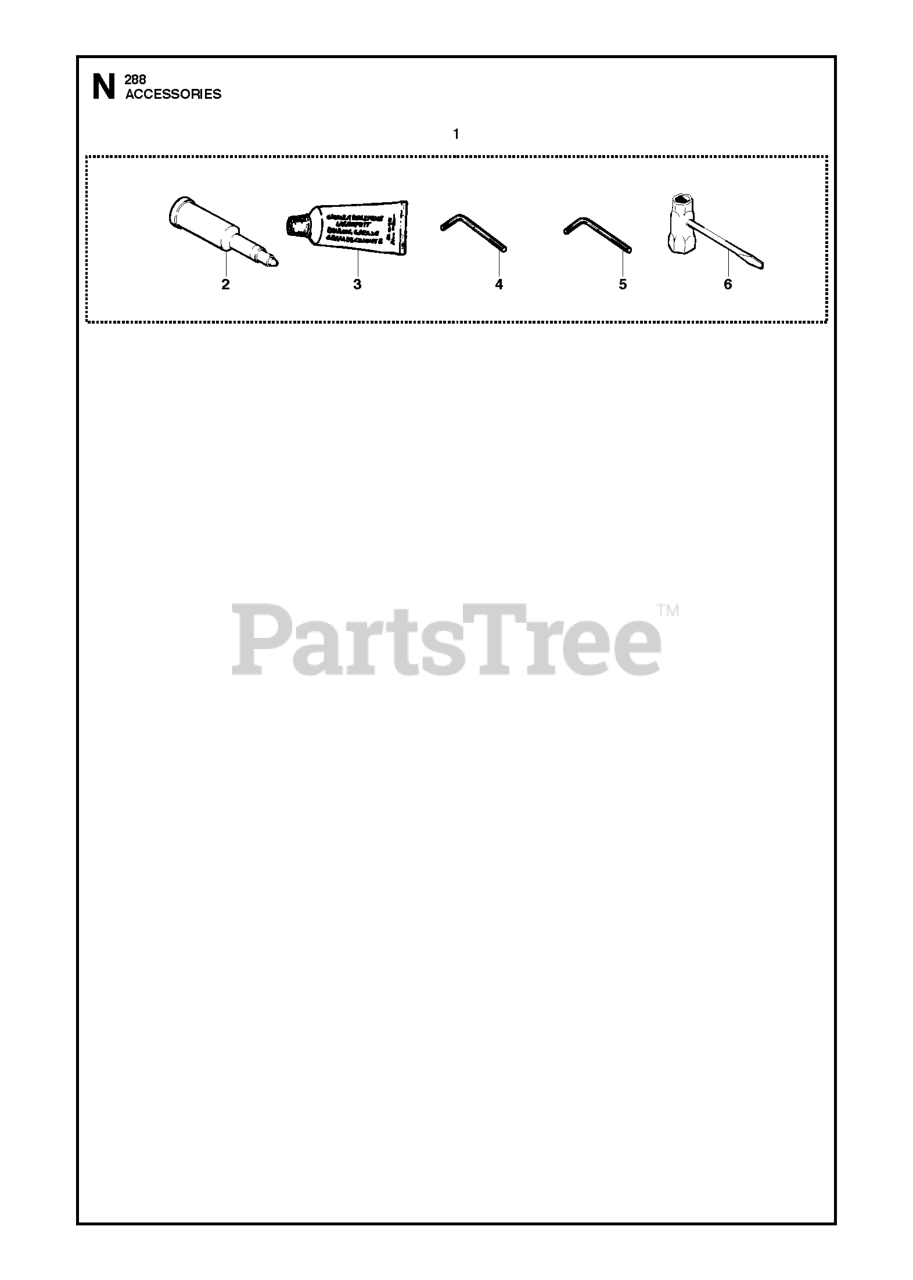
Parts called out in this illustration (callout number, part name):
1	TOOL KIT
2	Grease Gun
3	GREASE
4	L-SPANNER
5	L-SPANNER
6	COMBI TOOL
